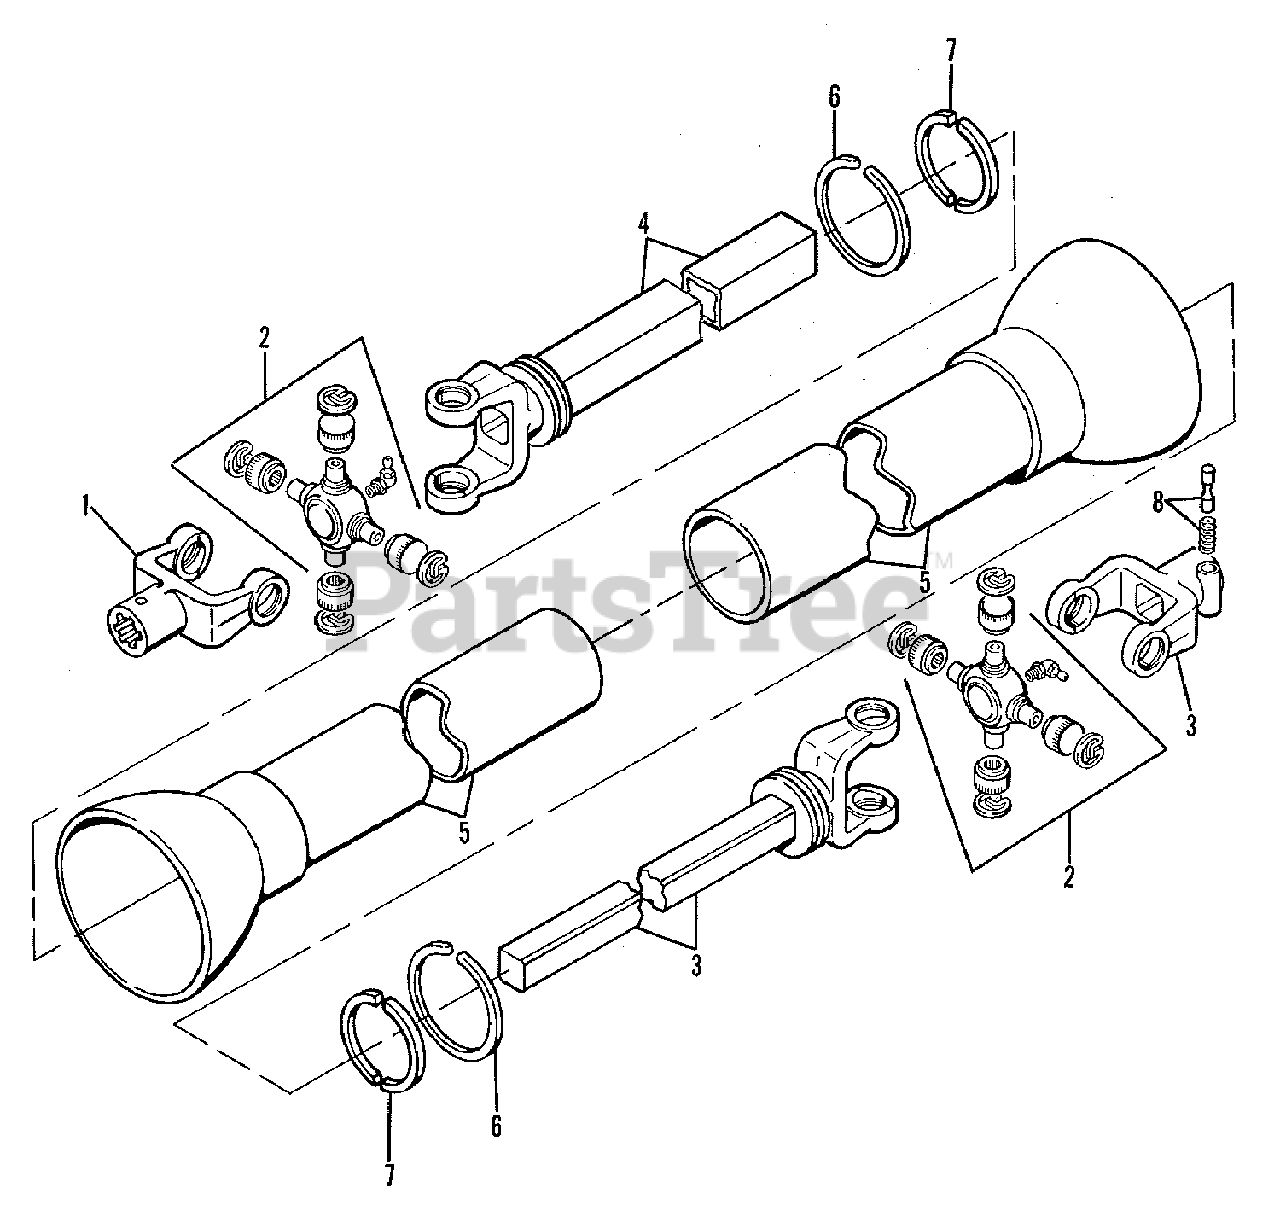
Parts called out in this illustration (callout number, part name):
1	YOKE (Gearbox End)
2	U-JOINT KIT
3	YOKE & SHAFT ASSEMBLY (Tractor End)
4	YOKE & SHAFT ASSEMBLY, Tubular (Gearbox End)
4	BOLT, Yoke & Input Shaft
4	LOCKWASHER, 1/4
4	NUT, Jam, 1/4NC
5	SHIELD ASSEMBLY, Complete
6	RETAINER, Sheild Bearing
7	BEARING, Shield
8	SPRING & PIN ASSEMBLY, Quick-Lock
